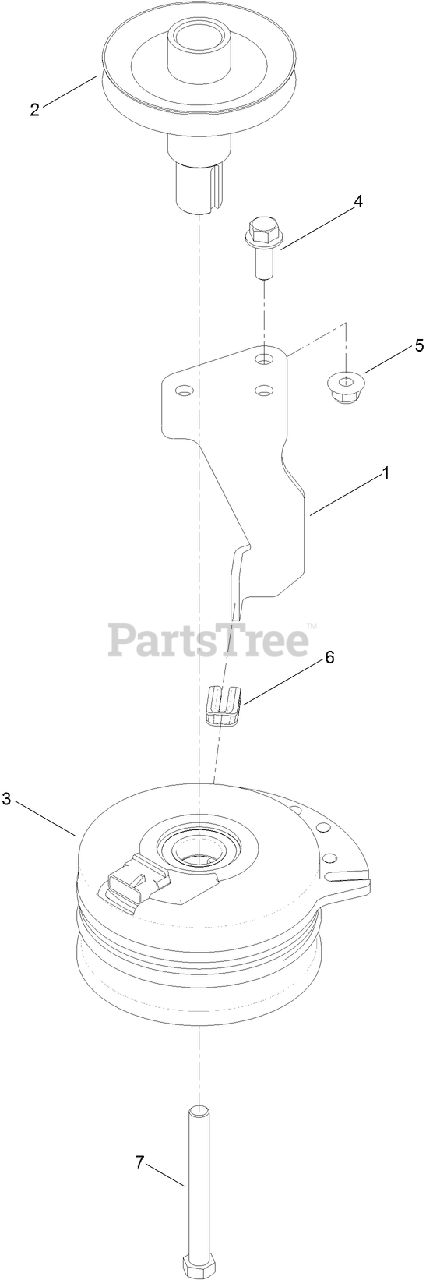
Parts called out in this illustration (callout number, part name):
1	STOP-CLUTCH (NARROW)
2	PULLEY-ENGINE
3	CLUTCH-ELECTRIC
4	SCREW-HHF
5	NUT-HF, NI
6	ISOLATOR-CLUTCH
7	SCREW-HH
